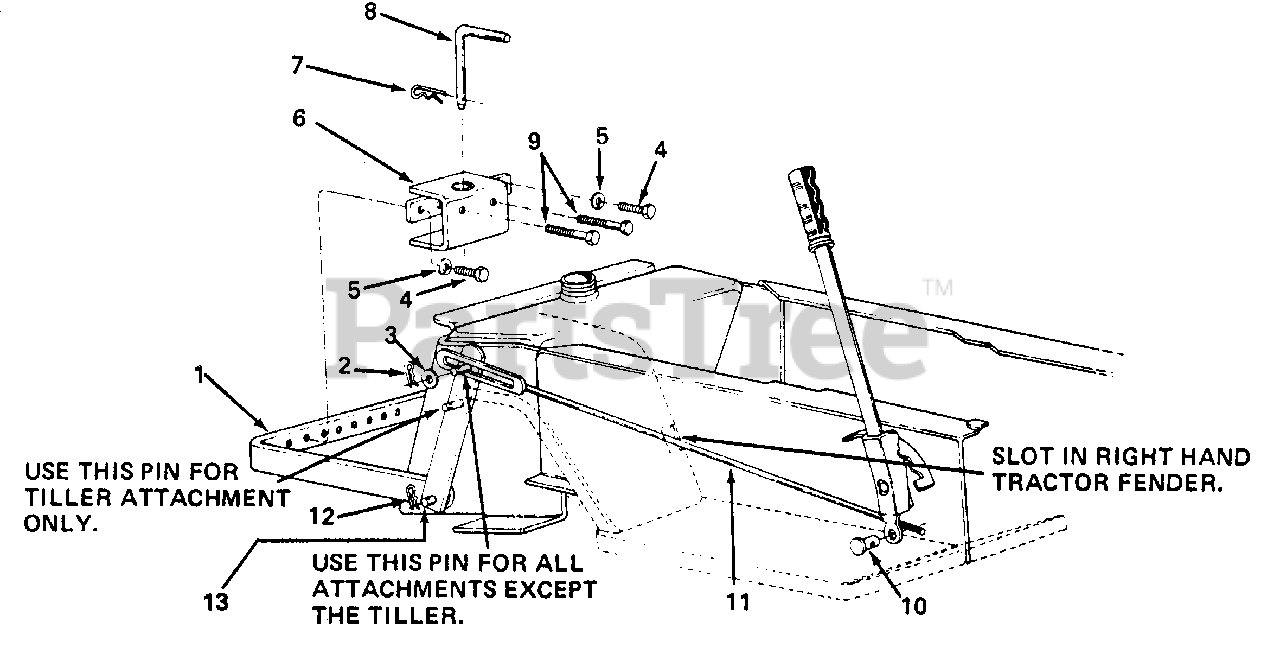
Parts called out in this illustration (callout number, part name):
3	Fl.-Wash. 1/2" I.D.
4	Hex Scr. 1/2-13 x 1.00" Lg. *
5	L.-Wash. 1/2" Scr.*
8	Hitch Pin
9	Hex Scr. 1/2-13 x 3.00" Lg. *
10	Adjustment Ferrule
13	Hitch Rod
